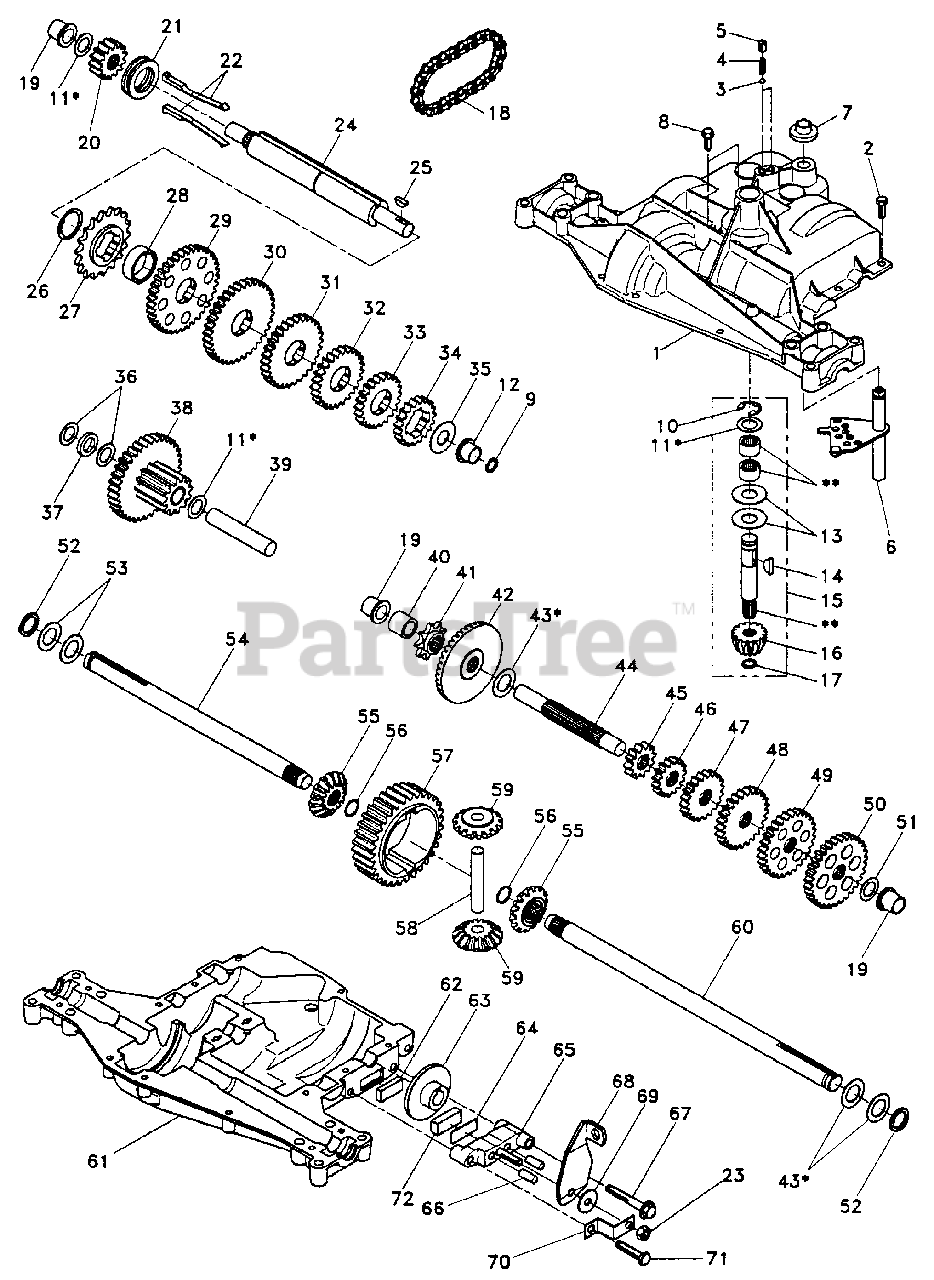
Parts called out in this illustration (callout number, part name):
1	Housing, Upper
2	Screw, Self-Tapping, Large 1/4-20 x .734
3	Ball, Detent
4	Spring, Detent
5	Screw, Set
6	Kit, Shifter Assembly
7	Boot, Shifter
8	Screw, Self-Tapping, with Sealer
9	Square Ring
10	Ring, Retaining
11	Assembly, Kit, Shim .625 Shaft
12	Bearing, Flange
13	Washer, Plain .632 x 1.38 x .046
14	Key, Woodruff, #9
15	Assembly, Kit, Input Shaft
16	Pinion, Bevel, 14 Teeth
17	Ring, Retaining
18	Chain, 24 Pitches
19	Bearing, Flange
20	Gear, Spur, 14 Teeth
21	Collar, Clutch
22	Assembly, Kit, Clutch Keys
23	Locknut 5/16-24
24	Shaft, Intermediate
25	Key, Woodruff, #61
26	Ring, Retaining
27	Sprocket, 18 Teeth (Reverse)
29	Gear, Spur, 37 Teeth (1st)
30	Gear, Spur, 35 Teeth (2nd)
31	Gear, Spur, 30 Teeth (3rd)
32	Gear, Spur, 25 Teeth (4th)
33	Gear, Spur, 22 Teeth (5th)
34	Gear, Spur, 19 Teeth (6th)
35	Washer, Plain .640 x 1.37 x .061
36	Washer, Plain .632 x 1.00 x .026
37	Spacer .630 x 1.00 x .169
38	Assembly, Gear, Combination of 12 Teeth and 35 Teeth
39	Shaft, Idler
40	Spacer .635 x .875 x .755
41	Sprocket, 9 Teeth (Reverse)
42	Gear, Bevel, 42 Teeth
43	Assembly, Kit, Shim .750 Shaft
44	Shaft, Drive
45	Gear, Spur, 12 Teeth (1st)
46	Gear, Spur, 15 Teeth (2nd)
47	Gear, Spur, 20 Teeth (3rd)
48	Gear, Spur, 25 Teeth (4th)
49	Gear, Spur, 28 Teeth (5th)
50	Gear, Spur, 31 Teeth (6th)
51	Washer, Plain .632 x 1.00 x .060
52	Washer, Neoprene
53	Washer, Plain .758 x 1.25 x .031
54	Axle, L.H.
55	Gear, Miter, 15 Teeth
56	Ring, Retaining
57	Gear, Spur, 32 Teeth
58	Shaft, Cross
59	Gear, Miter, 15 Teeth
60	Axle, R.H.
61	Housing, Lower
62	Puck, Friction
63	Disc, Brake
65	Jaw, Brake
66	Pin, Dowel
67	Screw, Self-Tapping, Large 5/16-18 x 2.25
68	Lever, Actuating
69	Washer, Plain .321 x 1.00 x .055
70	Bracket, Anti-Rotation
71	Screw, Self-Tapping, Large 5/16-18 x 1.44
72	Puck, Friction
73	Grease
